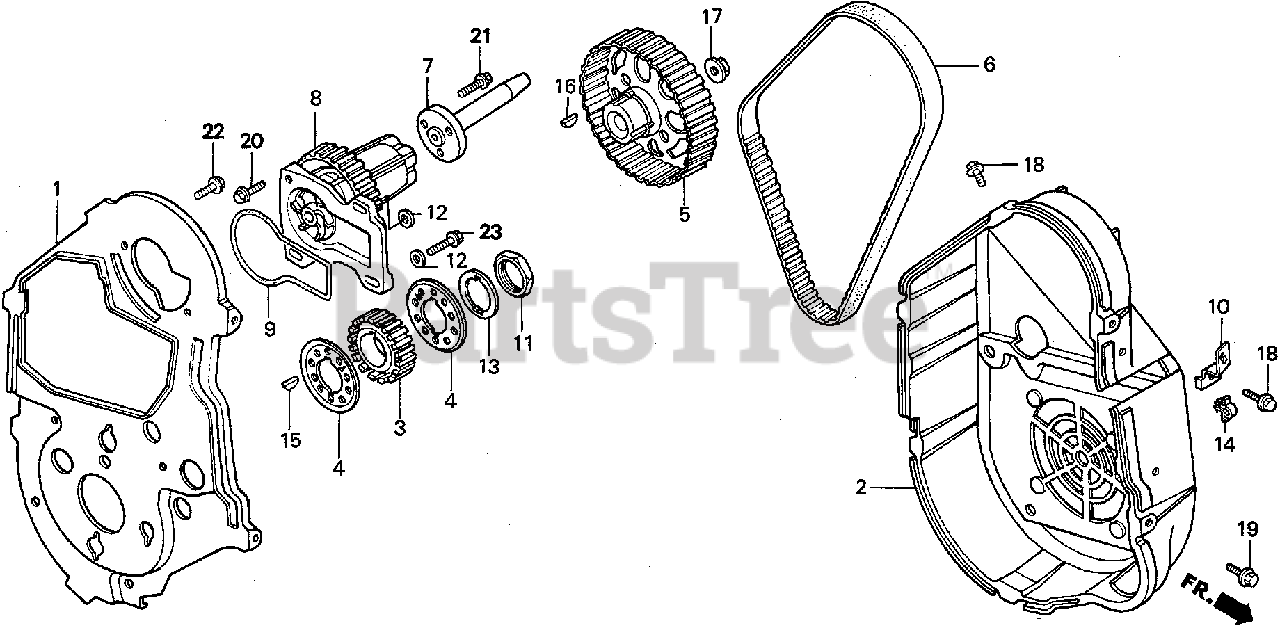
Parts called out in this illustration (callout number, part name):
1	COVER B, TIMING BELT
2	COVER A, TIMING BELT
3	PULLEY, TIMING
4	FLANGE, TIMING PULLEY
5	PULLEY, CAMSHAFT
6	BELT, TIMING
7	SHAFT, COOLING FAN
8	WATER PUMP
9	O-RING, WATER PUMP
10	BRACKET, IGNITION WIRE CLIP
11	NUT, LOCK (30MM)
12	WASHER, PLAIN (6.5X15)
13	WASHER, LOCK (30MM)
14	CLIP, ENGINE STOP SWITCH CORD
15	KEY, SPECIAL WOODRUFF (25X18)
16	KEY, WOODRUFF (16X12)
17	NUT, FLANGE (10MM)
18	BOLT, FLANGE (6X10)
19	BOLT, FLANGE (6X12)
20	BOLT, FLANGE (6X22)
21	BOLT, FLANGE (6X20)
22	BOLT, FLANGE (6X12)
23	BOLT, FLANGE (6X22)
